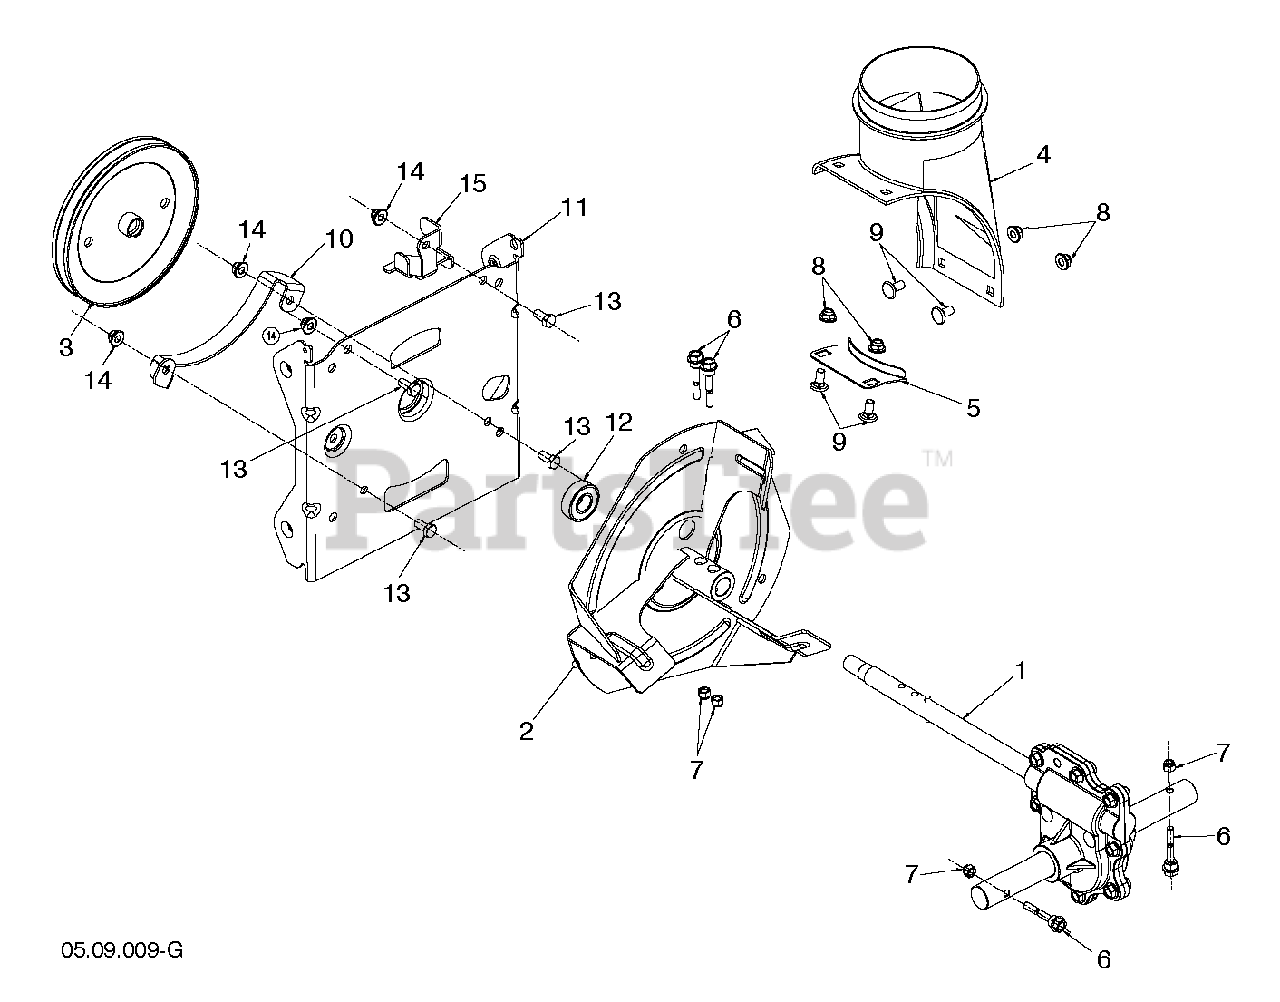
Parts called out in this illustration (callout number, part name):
1	Gear Box Assembly Alum
2	Impeller, Steel Snow Black
3	Screw-on Pulley, 7.3 5/8
4	Discharge Chute Base
5	BRACKET, CORNER DISCHARGE
6	BRACKET, CORNER DISCHARGE
7	LOCKNUT
8	Flange Hex Nut, Nylock Blk 5.16-1
9	Carriage Wafer Bolt, 5/16-18
10	BRACKET.BELT.KEEPER.LOWER.BLAC
11	Auger Housing Inter Bracket, Black
13	BOLT, HEX HEAD 5/16-18
14	NUTNYLOK.FLRANGE.5/16-18
15	Auger Belt Guide, Lower 479
